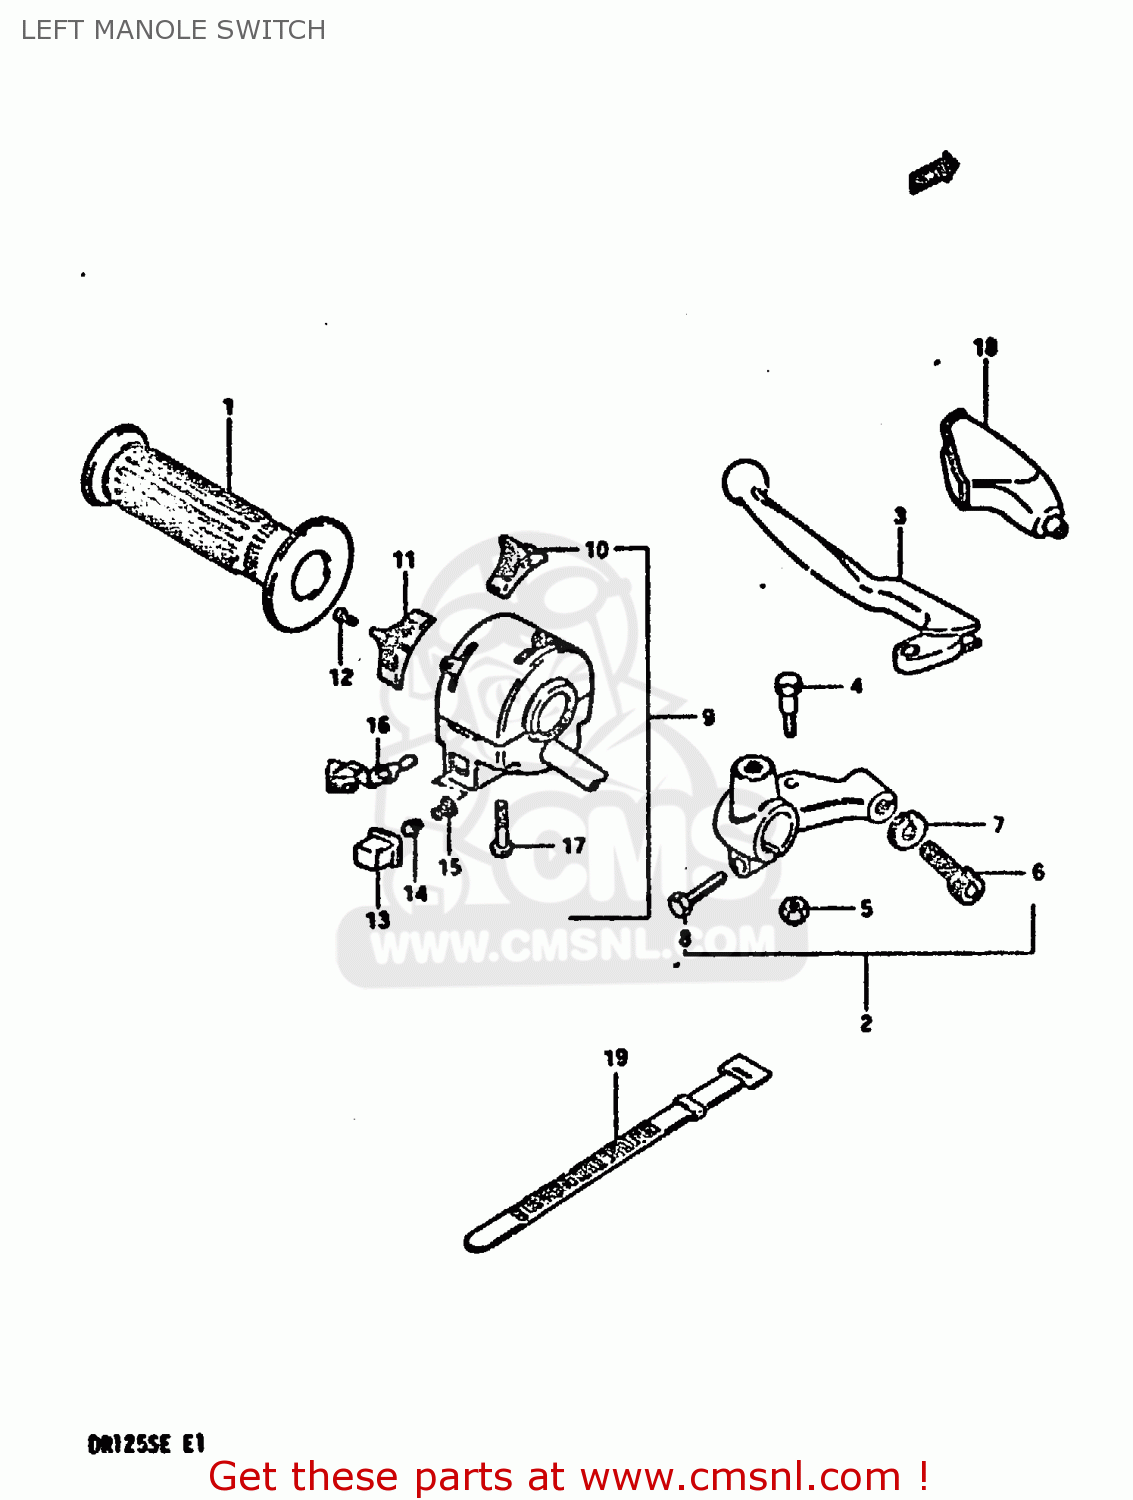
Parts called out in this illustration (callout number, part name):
1	GRIP,L
2	LEVER ASSY,CLUTCH
3	LEVER,CLUTCH
4	BOLT,LEVER
5	NUT 6MM
6	ADJUSTER,CABLE
7	NUT,CABLE ADJUSTER
8	BOLT,CLUTCH LEVER HOLDER
9	SWITCH ASSY, HANDLE LH
10	KNOB,LIGHTING SWITCH
11	KNOB,DIMMER SWITCH
12	SCREW
13	BUTTON,HORN
14	CONTACT
15	SPRING
16	KNOB,TURNSIGNAL
17	SCREW
18	COVER,CLUTCH LEVER
19	CLAMP(L:120)
